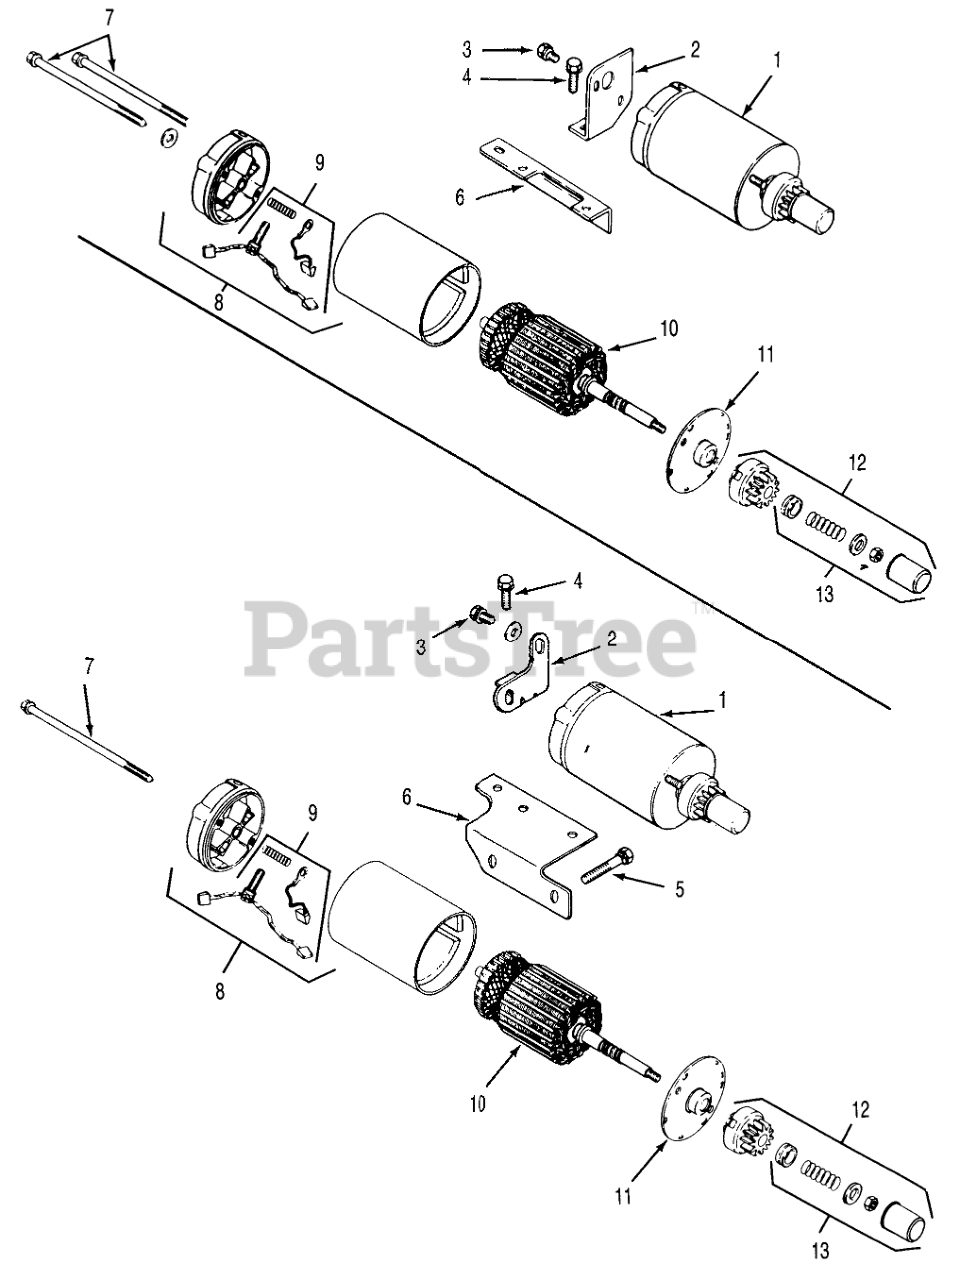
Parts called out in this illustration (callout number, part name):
1	Starter Assembly (Includes Items 9 thru 15)
2	Brace-Tail
3	Screw
4	Screw
5	Screw
6	Bracket-Solenoid
7	Bolt
8	Commutator End Cap Assembly (Includes Item 11)
9	Kit-Brush
10	Armature
11	Cap-Drive End
12	Drive Kit (Includes Item 15)
13	Kit-Drive Parts
